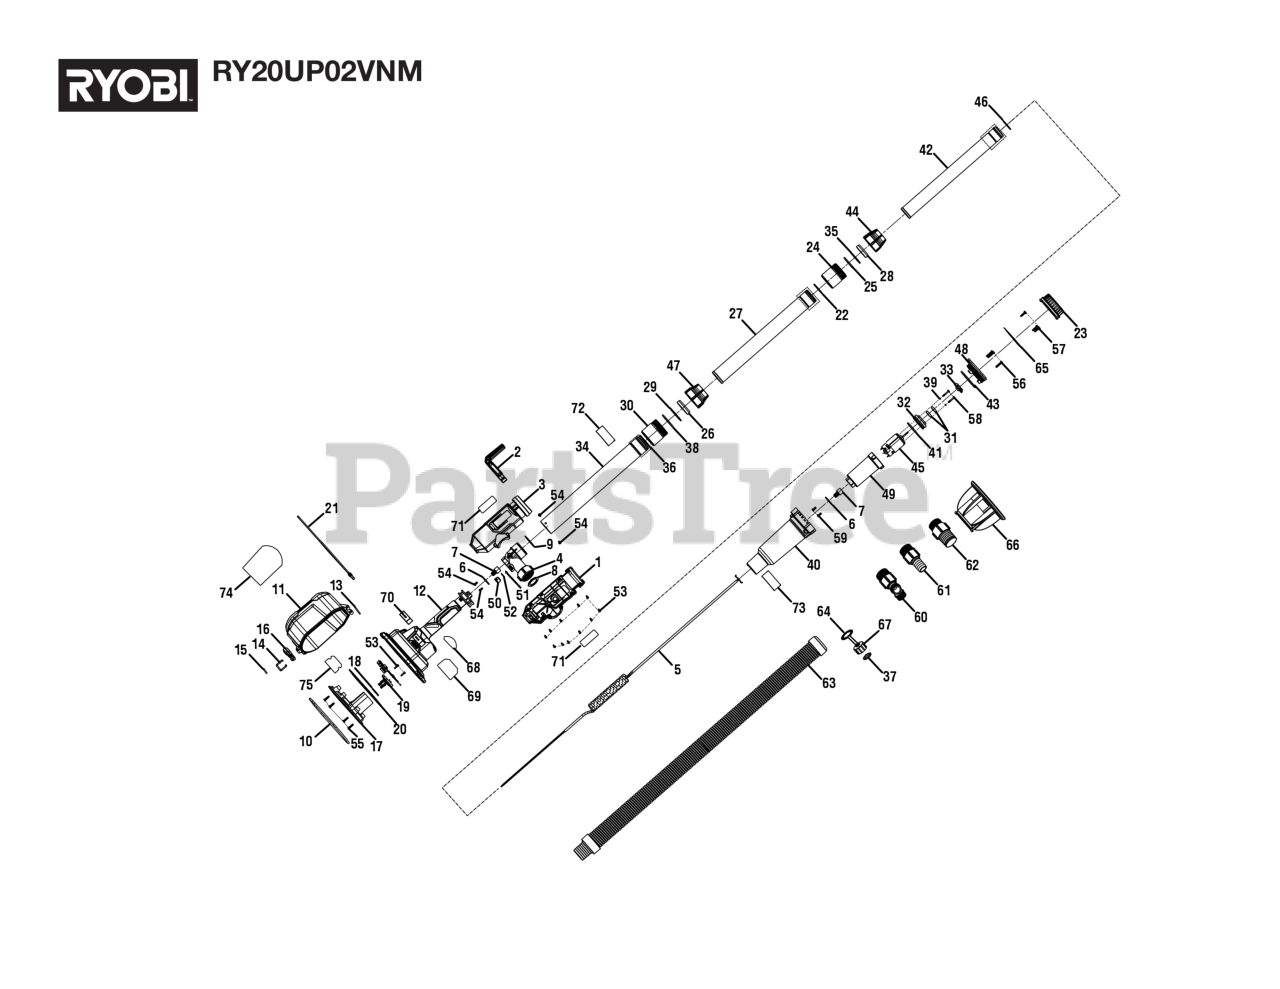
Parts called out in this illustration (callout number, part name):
1	Housing (Left, Inc. Key No. 71)
2	Barrel Hook
3	Housing (Right, Inc. Key No. 71)
4	Outlet & Coupler
5	Power Cable
7	Rubber Grommet
8	Rubber Gasket
9	O-Ring (37 x 1.8)
10	O-Ring Seal (ID142.5 x CS4)
11	Battery Door (Inc. Key No. 74)
12	Lower Housing (Inc. Key Nos. 68-70)
13	Battery Door Pin
14	Latch Locker
15	Latch Pin
16	Battery Door Latch
17	Battery Holder (Inc. Key No. 75)
18	O-Ring (24 x 2)
19	Terminal Assembly
20	O-Ring (106.2 x 2)
21	Wrist Lanyard
22	O-Ring (35.5 x 1.8)
24	Interlock
25	O-Ring (35 x 2.65)
26	Locking Collar
27	Center Tube
28	Locking Collar
29	Compression Ring (ID40.5 x OD47.5 x 2t)
30	Interlock
31	Rotary Shaft Seal
32	Motor Cover
34	Upper Tube (Inc. Key No. 72)
35	Compression Ring (ID35.5 x OD42.5 x 2t)
36	O-Ring (41 x 1.78)
37	Rubber Gasket
38	O-Ring (40 x 2.65)
39	O-Ring (3 x 1)
40	Pump Housing (Inc. Key No. 73)
41	O-Ring (36 x 2.65)
42	Lower Tube
43	O-Ring (55 x 2.65)
45	18V Motor
46	O-Ring (30.5 x 1.8)
48	Pump Cover
50	Umbrella Valve Seat
51	Tank Cap Umbrella Valve
52	O-Ring (10.6 x 1.8)
53	Screw (M3 x 12 mm)
54	Screw (M4 x 8 mm)
55	Screw (M4.2 x 15 mm, Phillips Hd. S.T.)
56	Screw (M4 x 20 mm, T20 Torx Pan Hd.)
57	Screw (M4.2 x 15 mm, T20 Torx Pan Hd.)
58	Screw (M3 x 20 mm, T20 Torx Pan Hd.)
59	Screw (M4 x 10 mm, T20 Torx Pan Hd.)
60	3/4 in. Adapter Splitter
61	1 in. Barbed Hose Coupler
62	Pool Hose Coupler
63	Pool Hose
64	3/4 in. Tether
65	Filter Net
66	Mud Straining Filter
67	3/4 in. Cap
68	Task Light Led Label
69	On Off Label
70	Timer Label
71	Logo Label
72	Do Not Submerge Label
73	Do Not Twist Label
74	Icon / Warning Label
75	Data Label
